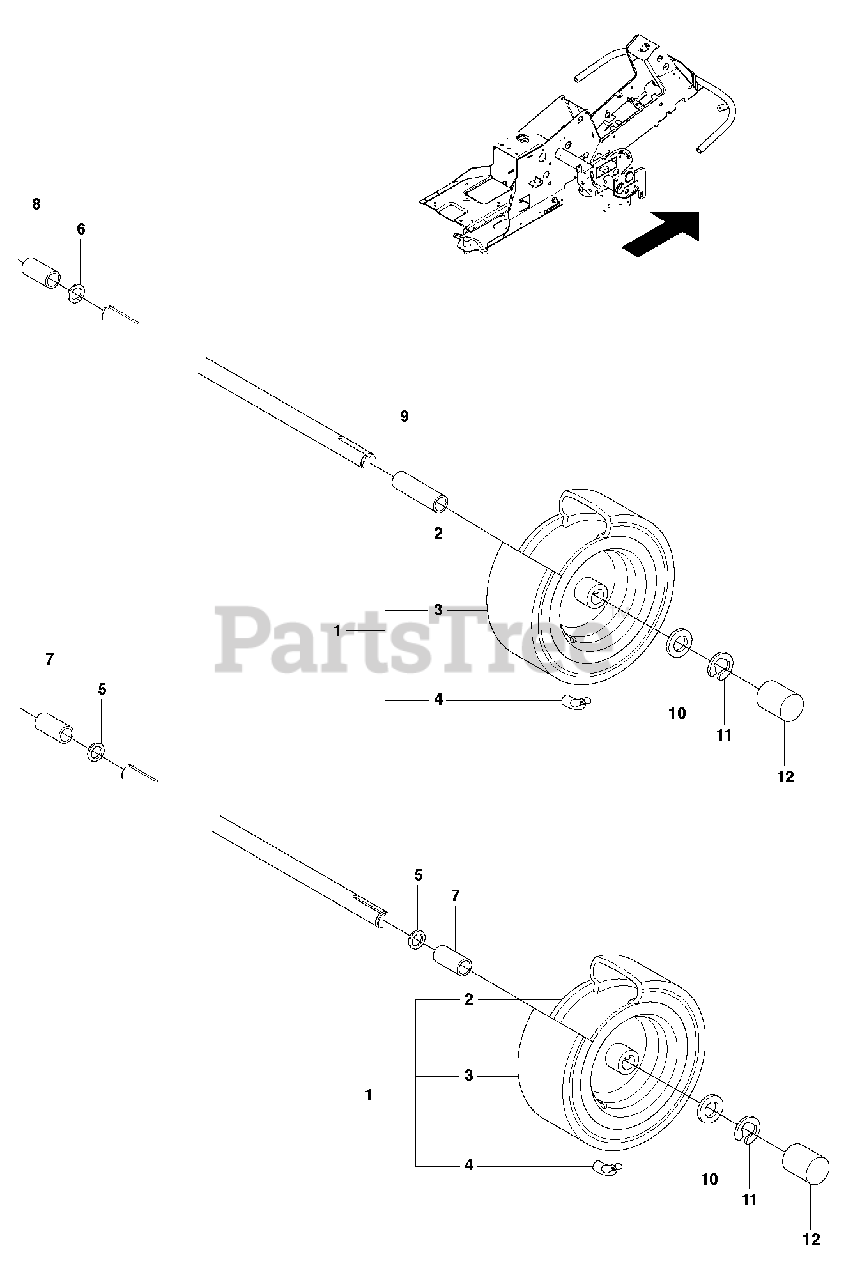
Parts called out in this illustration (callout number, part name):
2	RIM
7	SPACE SLEEVE
11	RETAINING RING
